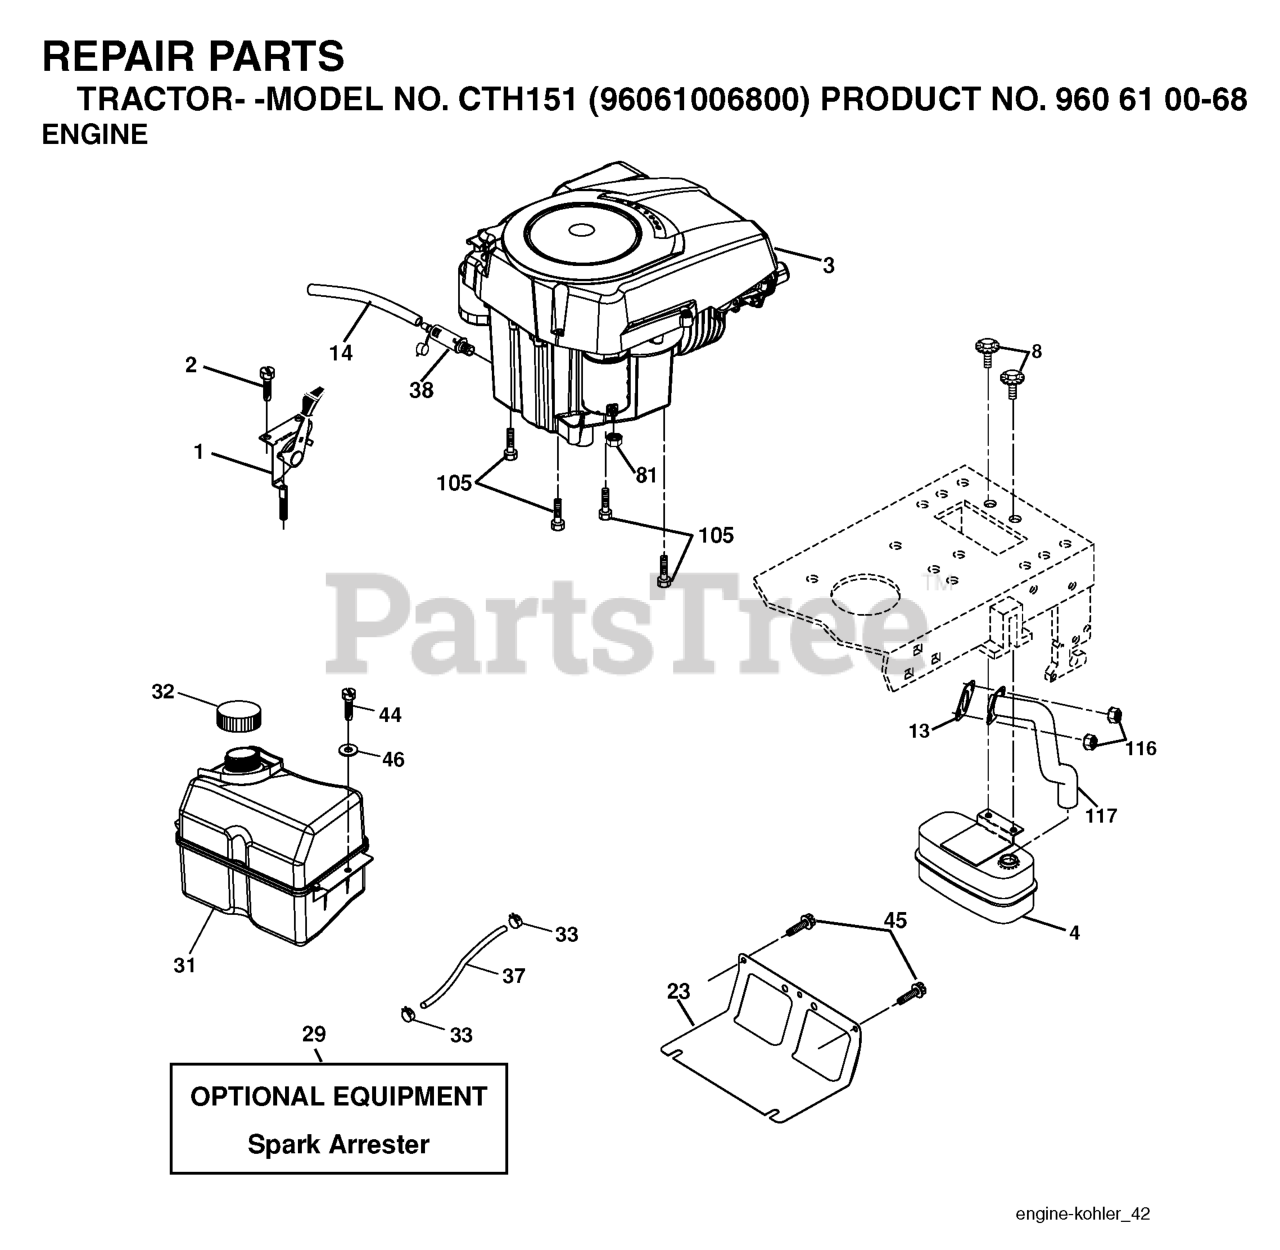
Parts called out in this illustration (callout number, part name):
1	CONTROL.THROTTLE.LT/YT
2	SCREW
4	MUFFLER.SINGLE.CYL.KOHL/B&S
8	BOLT.5/16-18UNCX3/4 W/SEMS.BLK
13	GASKET.EXHAUST.KOHLER
14	TUBE, DRAIN OIL ASM.
23	SHIELD.BROWNING.DBR.GUARD
29	KIT.SPARK ARRESTOR 794945 B&S
31	TANK FUEL
32	FUEL CAP
33	HOSE CLAMP
37	LINE.FUEL.20
38	PLUG DRAIN OIL EASY
44	SCREW HEXWSHR 1/4-20X3/4
45	SCREW, 3/8-16X3/4
81	NUT
105	SCREW 3/8-16X1
116	NUT.HEX.FLANGE.TOPLOCK
117	RP.TUBE.EXHAUST.KOHL.COURAGE
